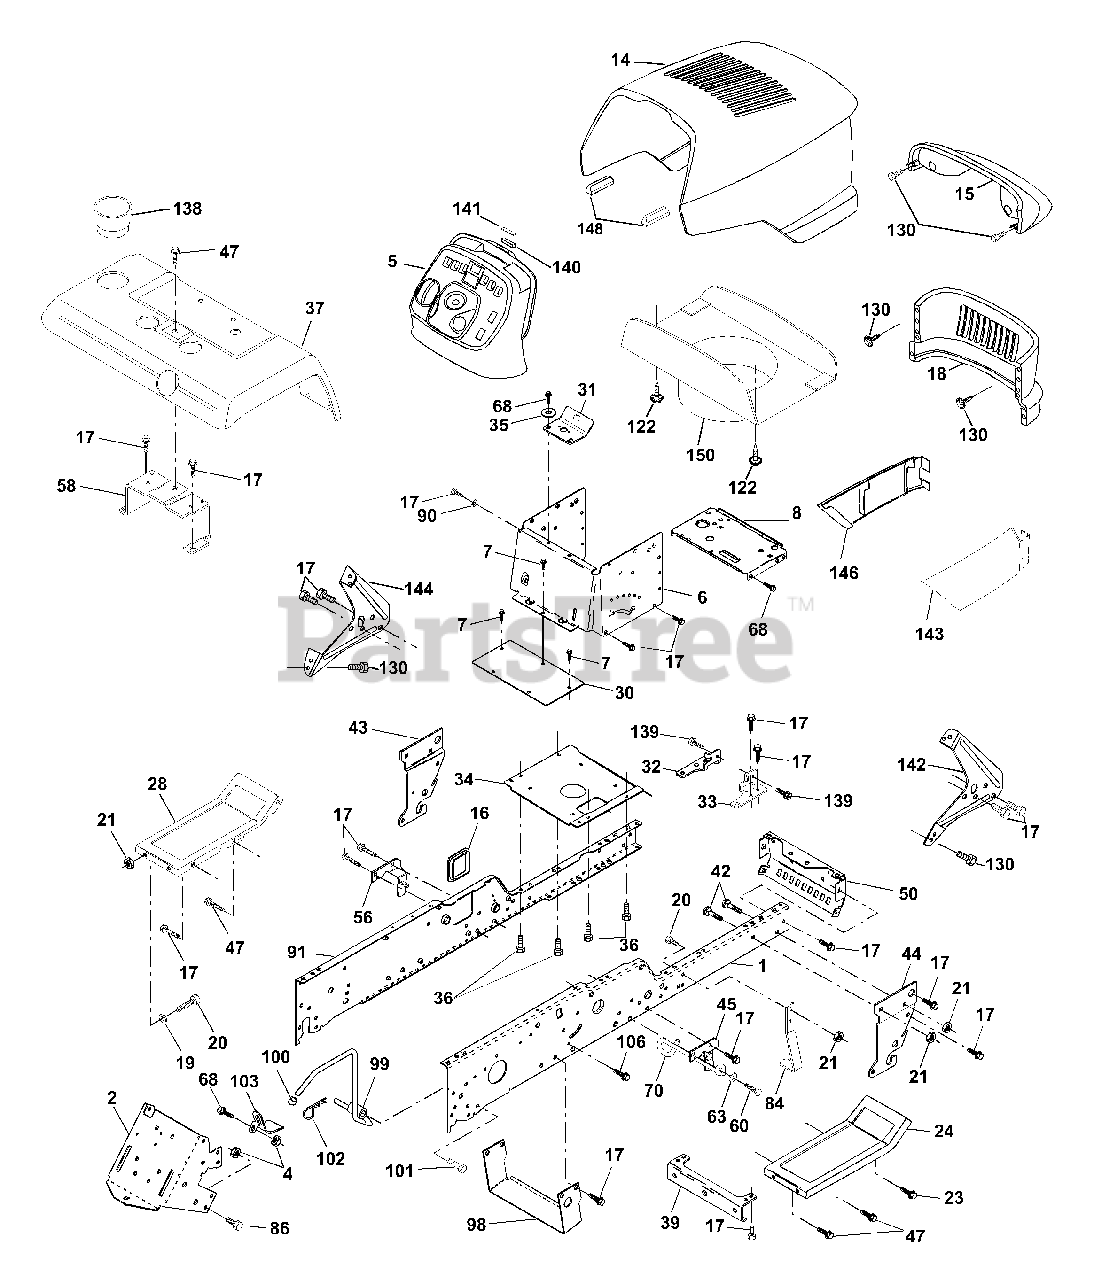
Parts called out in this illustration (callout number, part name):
1	Rail, Frame RH
2	Drawbar, Gt
4	Nut, Lock Hex 7/16 Unc
5	Dash, Plastic
6	Dash, 1PCS, Lower
7	Screw, Thd Cut 1/4-20 x 1/2
8	Support, Battery
14	Hood Asm., Pnt
15	Lens, Headlight Bar
16	Cover, Access
17	Screw, 3/8-16 x 3/4
18	Grille
19	Washer 13/32 x 13/16 x 12 Ga.
20	Bolt, Fin Hex 3/8-16 x 1
21	Nut, Crownlock 3/8-16
23	Screw 3/8-16 x 1-1/2
24	Footrest, RH
28	Footrest, LH
31	Bracket Supt 1-pc Vgt Steering
32	Bracket, Frame Pivot Lh
33	Bracket, Frame Pivot Rh
34	Plate Asm Engine Chassis
35	Washer 11/32 x 11/16 x 16 Ga.
36	Screw 5/16-18 x 3/4
37	Fender, Pnt.
39	Bracket, Axle Front
42	Bolt Rdhd Sqnk 3/8-16 Unc x 1
43	Bracket, Spnsn Front Lh
44	Bracket, Spnsn Front Rh
45	Bracket Asm., Susp Chassis Rh
47	Screw Thdrol 3/8-16 x 1/2
50	Bracket, Chassis Front
56	Bracket Asm., Susp Chassis Lh
58	Bracket Asm., Fender
60	Screw 3/8-16 x 1-1/4
63	Washer 13/32 x 1 x 14 Ga.
68	Screw, 5/16-18 x 1/2
70	Guide, Belt Mid Span
84	Stop, Over Center Mower
86	Bolt, Fin Hex 7/16-14 Unc x 1
90	Washer, Lock External Tooth 3/8
91	Rail, Frame Lh
98	Bracket Chassis Skid
99	Rod Asm. Bypass
100	Cad By pass Rod
101	Screw Thdrol. 3/8-16 x 1-3/4
102	Retainer Spring 1"
103	Bracket Lock Bypass
106	Screw Thdrol Hex Head Zinc
122	Screw Hex WSHD 8-18 x 7/8
130	Screw Hw Hd Hi-Lo #13-16 x 3/4
138	Cupholder
139	Bolt Shoulder 5/16-18
140	Magnet Stealth
141	Striker Plate
142	Bracket Dash Stealth RH
143	Skirt Grille RH
144	Bracket Dash Stealth LH
146	skirt Grille RH
148	Extrusion Bumper
150	Duct Heat Hood
